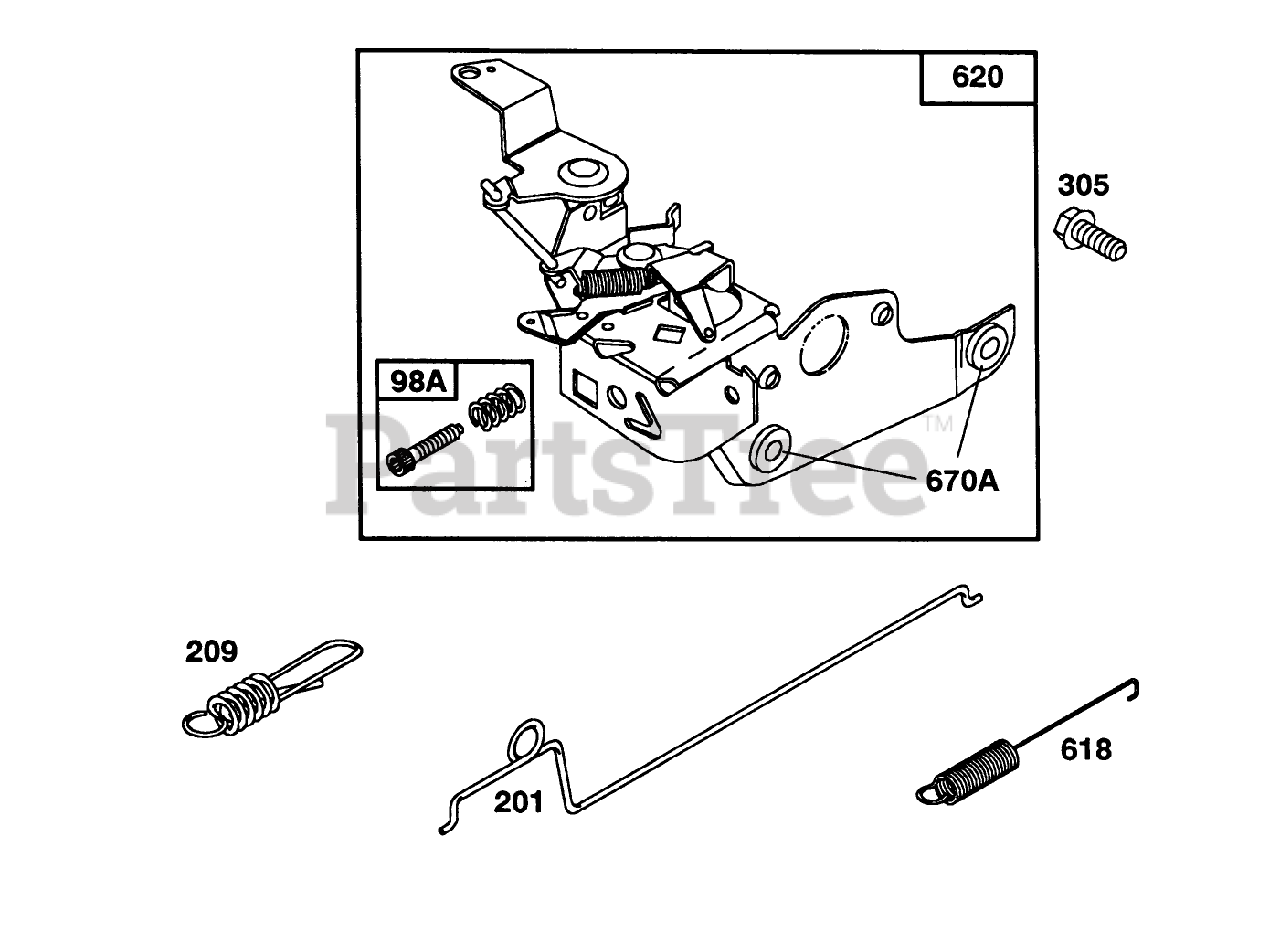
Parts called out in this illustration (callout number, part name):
98A	Screw Assy.
201	Link-Govemor
209	Spring-Govemor
305	Screw-Sem
618	Spring-Choke
620	Bracket Assembly
670A	Spacer
